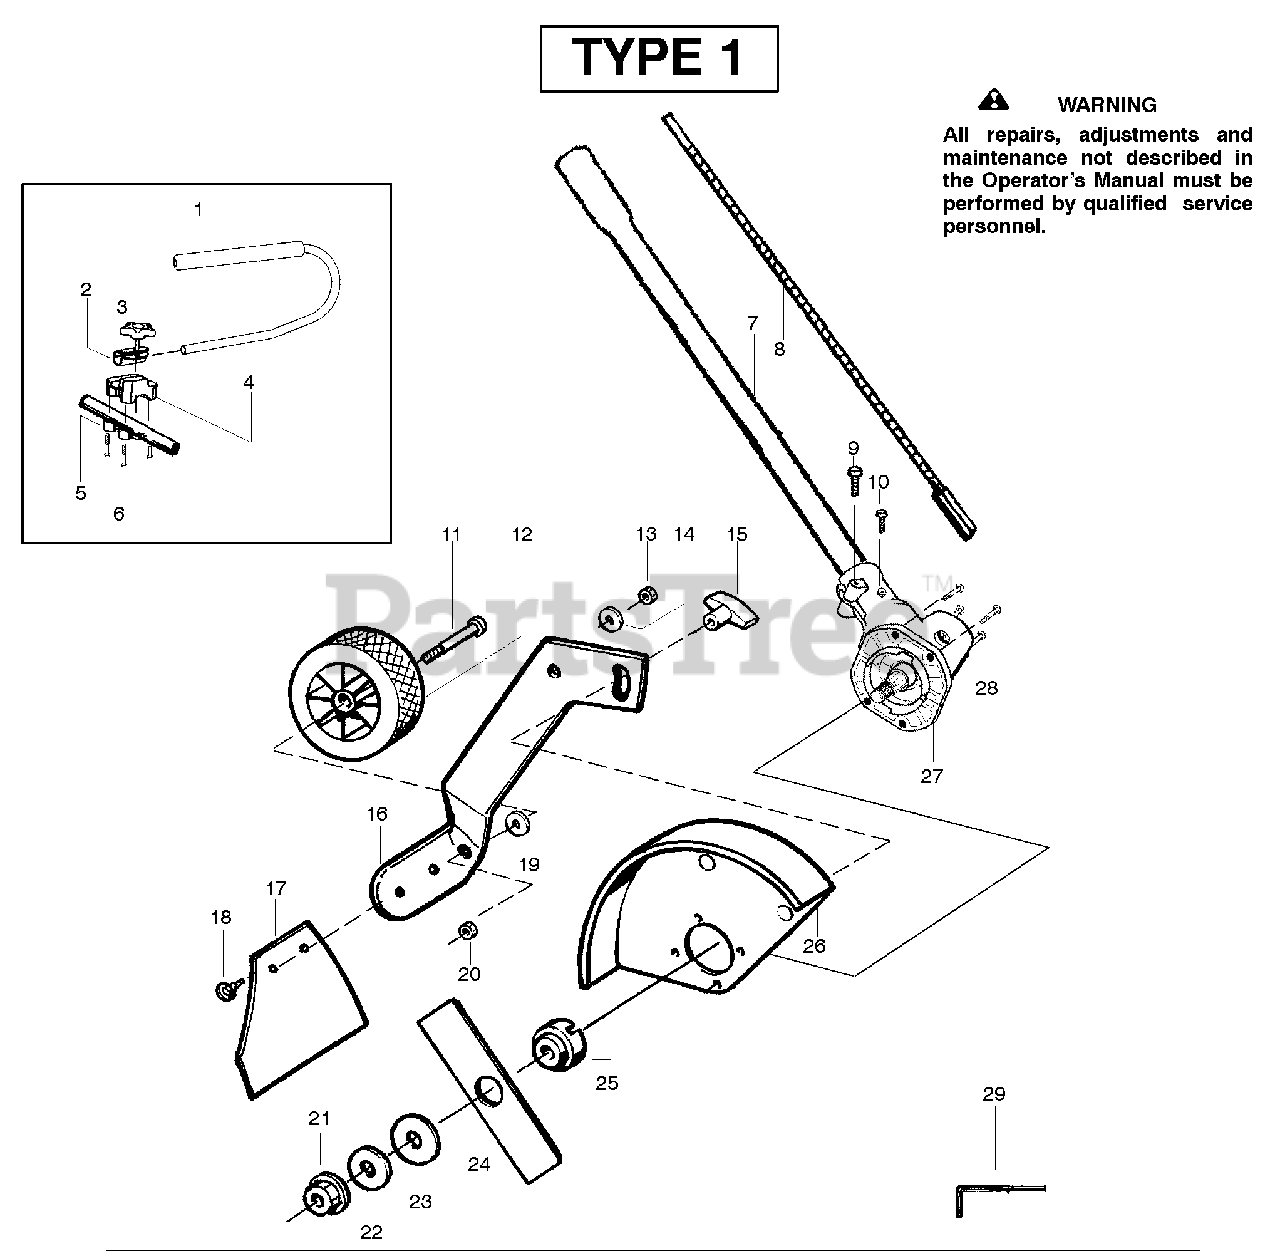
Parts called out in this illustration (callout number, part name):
1	Kit-Handlebar
2	Clamp-Handlebar
3	Knob
4	Base-Clamp
5	Kit-Clamp-Tube
6	Screw
7	Assy.-Driveshaft
8	Flexshaft-Split boom
10	Screw-Alignment
11	Bolt-Shoulder Axle
12	Wheel-4" (rubber)
16	Bracket-Adj. Wheel
17	Kit-Mud Flap
18	Fastener-Mud Flap
21	Nut-Flange (L.H.)
22	Washer-Belleville
26	Kit-Edger Guard
29	Wrench-Hex (5/32")
